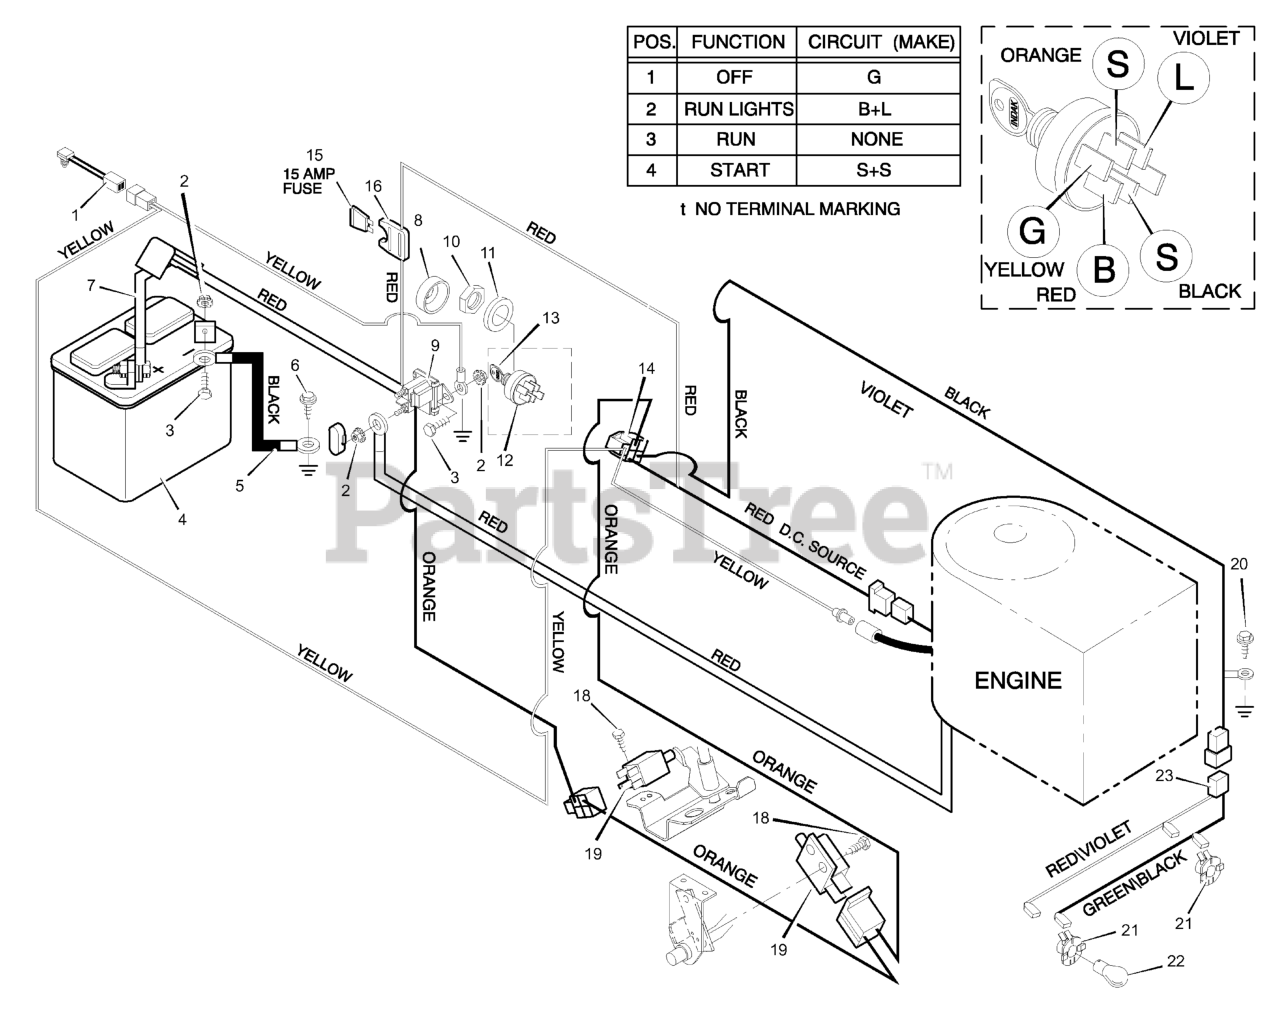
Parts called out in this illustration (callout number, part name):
1	Switch, Seat Sensor
2	Locknut
3	Bolt, Hex
4	Battery
5	Cable, Battery Ground
7	Cable, Red Battery
8	Cap, Ignition
9	Solenoid
10	Nut
12	Switch, Ignition
13	Key, Ignition
14	Harness, Chassis Wire
16	Holder, Fuse
17	Switch, Clutch
19	Switch, Clutch
20	Screw
21	Socket, Light
22	Bulb, Light
23	Harness, Light Wire
24	Cover, Terminal
26	Ammeter
